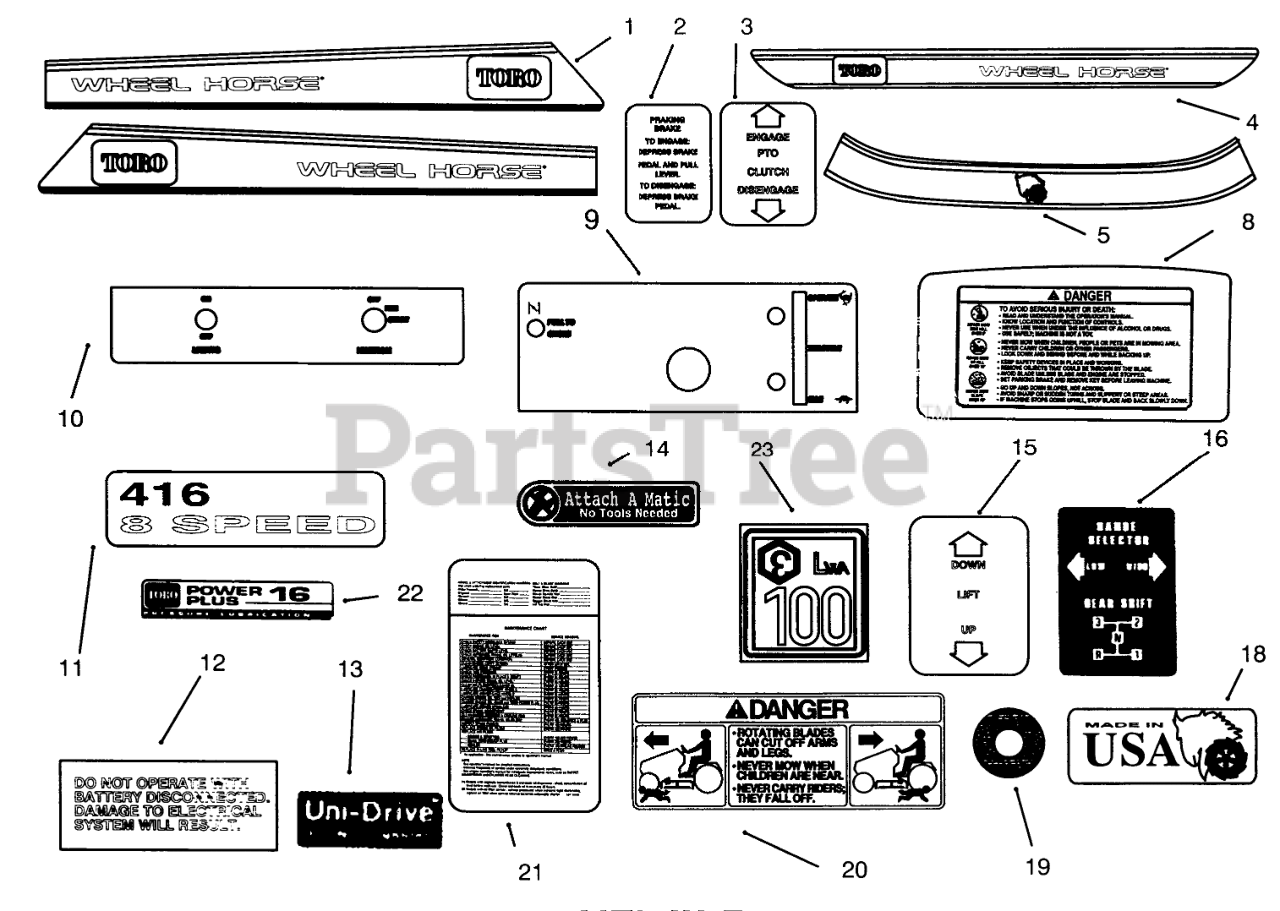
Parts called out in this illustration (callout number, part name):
1	DECAL - RH HOOD TOP
2	DECAL-PARKING, BRAKE
3	DECAL PTO CLUTCH
4	DECAL - REAR FENDER
5	DECAL-FRONT HOOD, TOP
8	DECAL - DANGER
9	DECAL-LOWER DASH
10	Decal-Black Plate
11	DECAL - MODEL 416-8
12	DECAL ELECT SYSTEM
13	Decal-Unidrive
14	DECAL-ATTACH A-MATIC
15	DECAL-LIFT
16	DECAL-SHIFT PATTERN
18	DECAL - USA
19	Decal-Air Cleaner
20	DECAL-DANGER
21	Decal-Maintenance
22	DECAL-PWR PLUS 16 PL
23	DECAL-EUROPE
